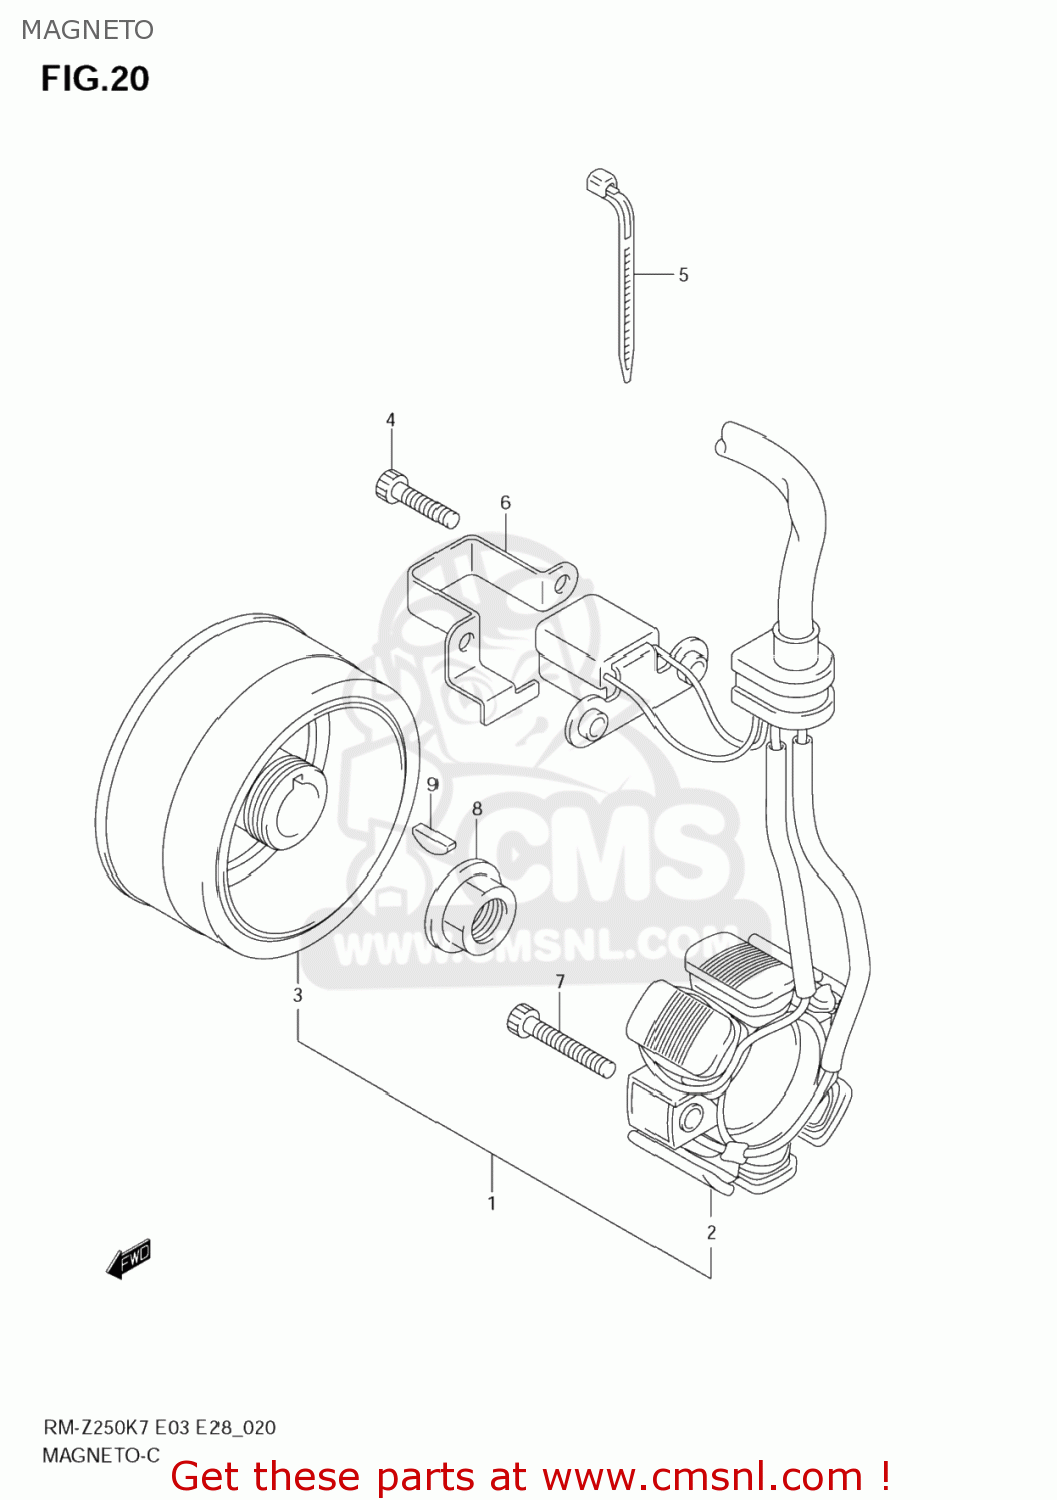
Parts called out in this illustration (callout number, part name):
1	MAGNETO ASSY
2	STARTER ASSY
3	ROTOR ASSY
4	CLAMP,MAGNETO LEAD
5	CLAMP(L:125)
6	BOLT
7	BOLT(5X25)
8	NUT
9	KEY
